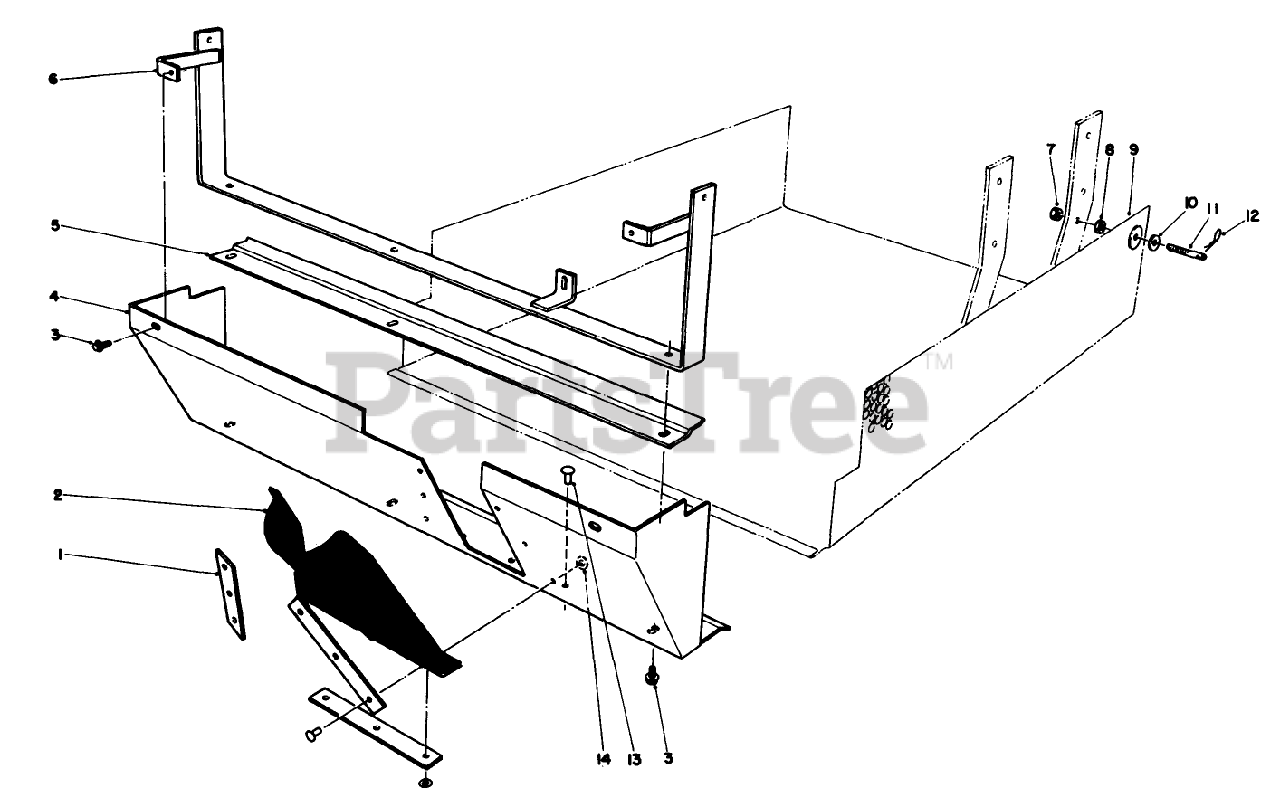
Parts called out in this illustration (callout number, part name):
1	SCREW-HH
2	DECAL-DANGER
5	BUSHING-PULLEY
6	PULLEY-IDLER
7	NUT-LOCK, SIDE
8	WASHER-FLAT
9	SCREW-SHOULDER
10	SPRING-EXTENSION, DECK
12	NUT-LOCK, NI
13	DECAL-DANGER
14	DECAL-TORQUE
15	FITTING-GREASE
16	NUT-HEX
17	WASHER
19	V-BELT, DECK
20	SEAL-OIL
21	BEARING ASM
22	SCREW-CARR
23	DECAL-WARNING
25	WASHER-FLAT
26	HOUSING-SPINDLE
27	NUT-HF
28	SPACER
29	SHAFT
32	WASHER-LOCK
33	Screw-Blade
34	DECAL-DANGER, THROWN OBJECT
36	SCREW-HH
37	SHAFT-ROLLER
38	PIN-SPECIAL
39	PIN-COTTER
40	ROLLER
